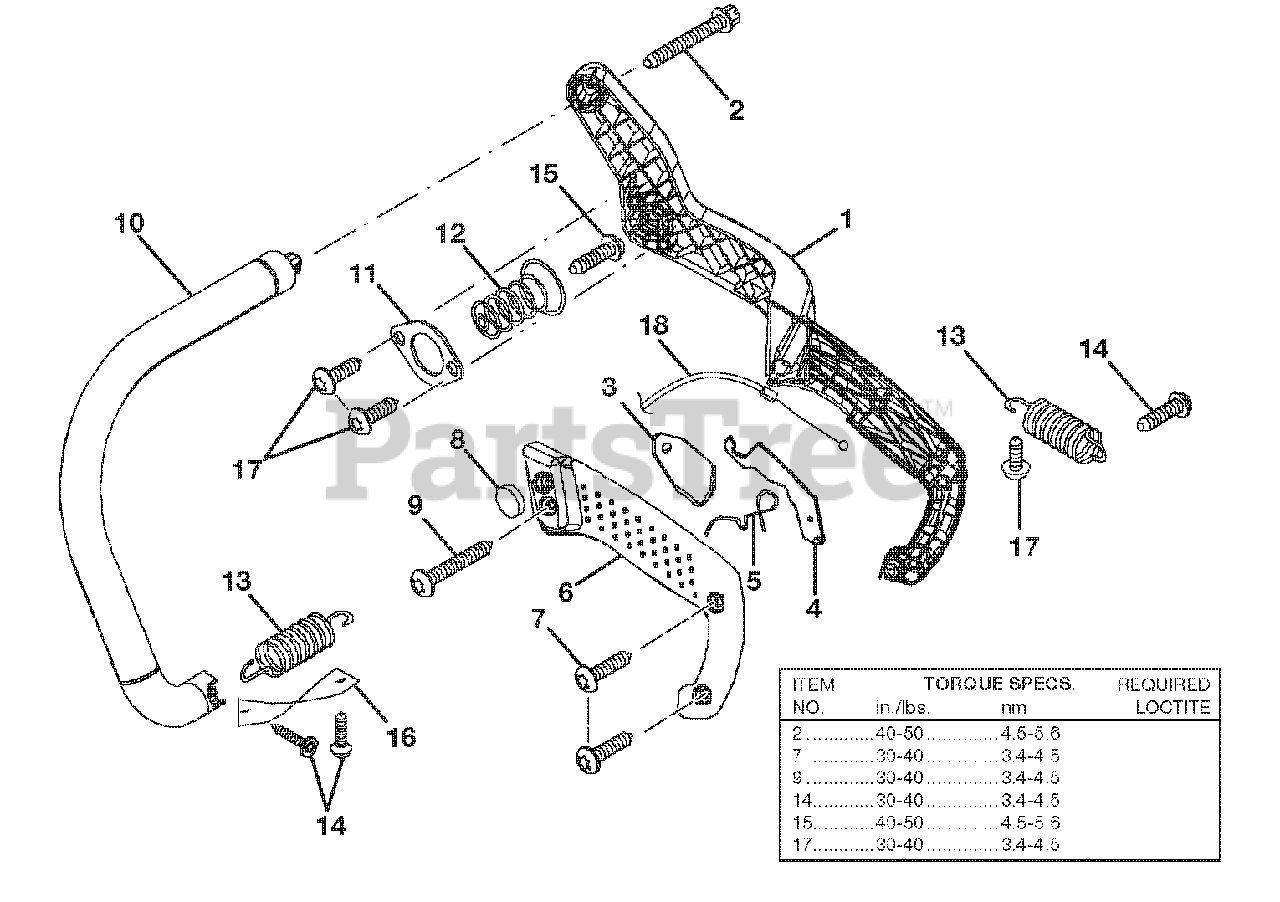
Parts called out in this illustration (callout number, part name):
1	REAR HANDLE
2	SCREW (12-14 x 1-1/2 in.)
3	TRIGGER, THROTTLE
4	THROTTLE LOCK OUT
5	TORSION SPRING
6	HANDLE COVER
7	SCREW (10-14 x 3/4 in.)
8	PLUG-PLASTIC
9	SCREW (10-14 x 1-3/8 in.)
10	FRONT HANDLE
11	ISOLATOR PLATE
12	UPPER ISOLATION SPRING
13	SPRING - ISOLATOR
14	SCREW (10-14 x 5/8 in.)
15	SCREW (10-24 x 5/8 in.)
16	SPRING RETAINER
17	SCREW (10-14 x 1/2 in.)
18	THROTTLE CABLE
